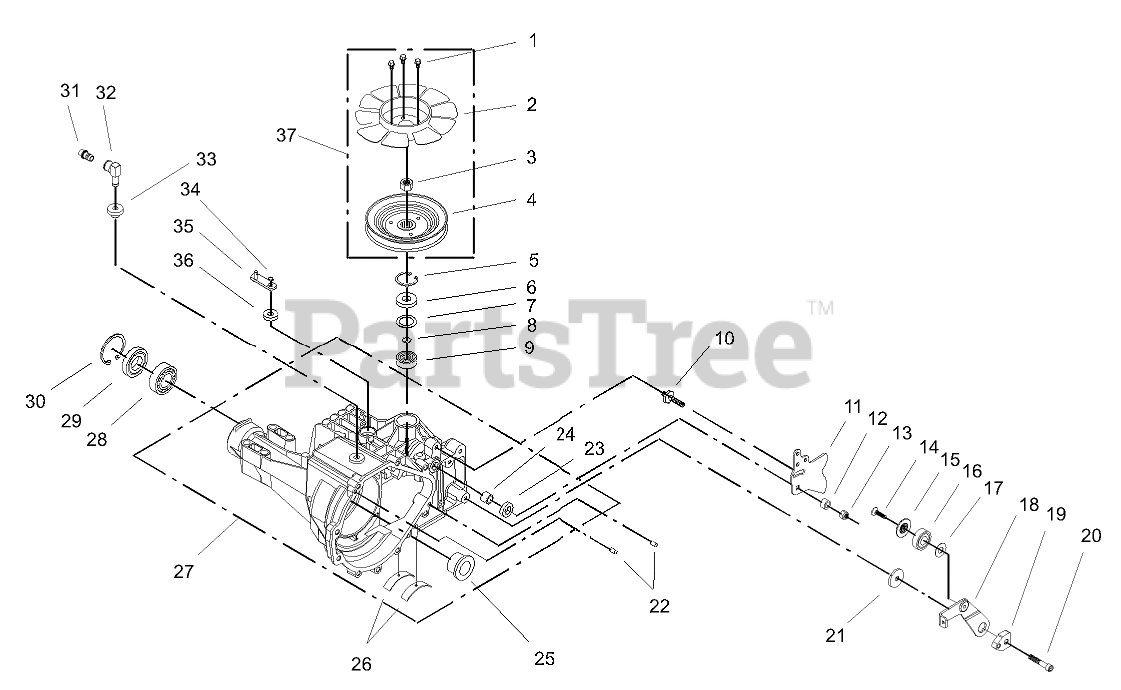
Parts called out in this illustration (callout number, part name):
3	NUT-HEX
4	PULLEY
5	RING-RETAINING
6	SEAL-LIP
7	SPACER
8	RING-WIRE, RETAINING
9	BEARING-SHAFT, BALL
11	ARM-CONTROL
12	SPACER-TRUNNION
13	NUT-HEX, LOCK
14	SCREW-COUNTERSUNK
15	SPACER-LOCATING
16	BEARING
17	WASHER
18	ARM-RETURN
19	PUCK-ADJUSTING
21	WASHER
23	SEAL-LIP
24	BUSHING-TRUNNION
25	BEARING-FLANGE
26	BEARING-CRADLE
27	MAIN HOUSING ASM
28	BEARING-BALL
30	RING-RETAINING
31	VENT CAP ASM
32	FITTING
33	BUSHING-RUBBER
34	RING-RETAINING
35	ARM-BYPASS
36	SEAL-LIP
37	FAN/PULLEY KIT
